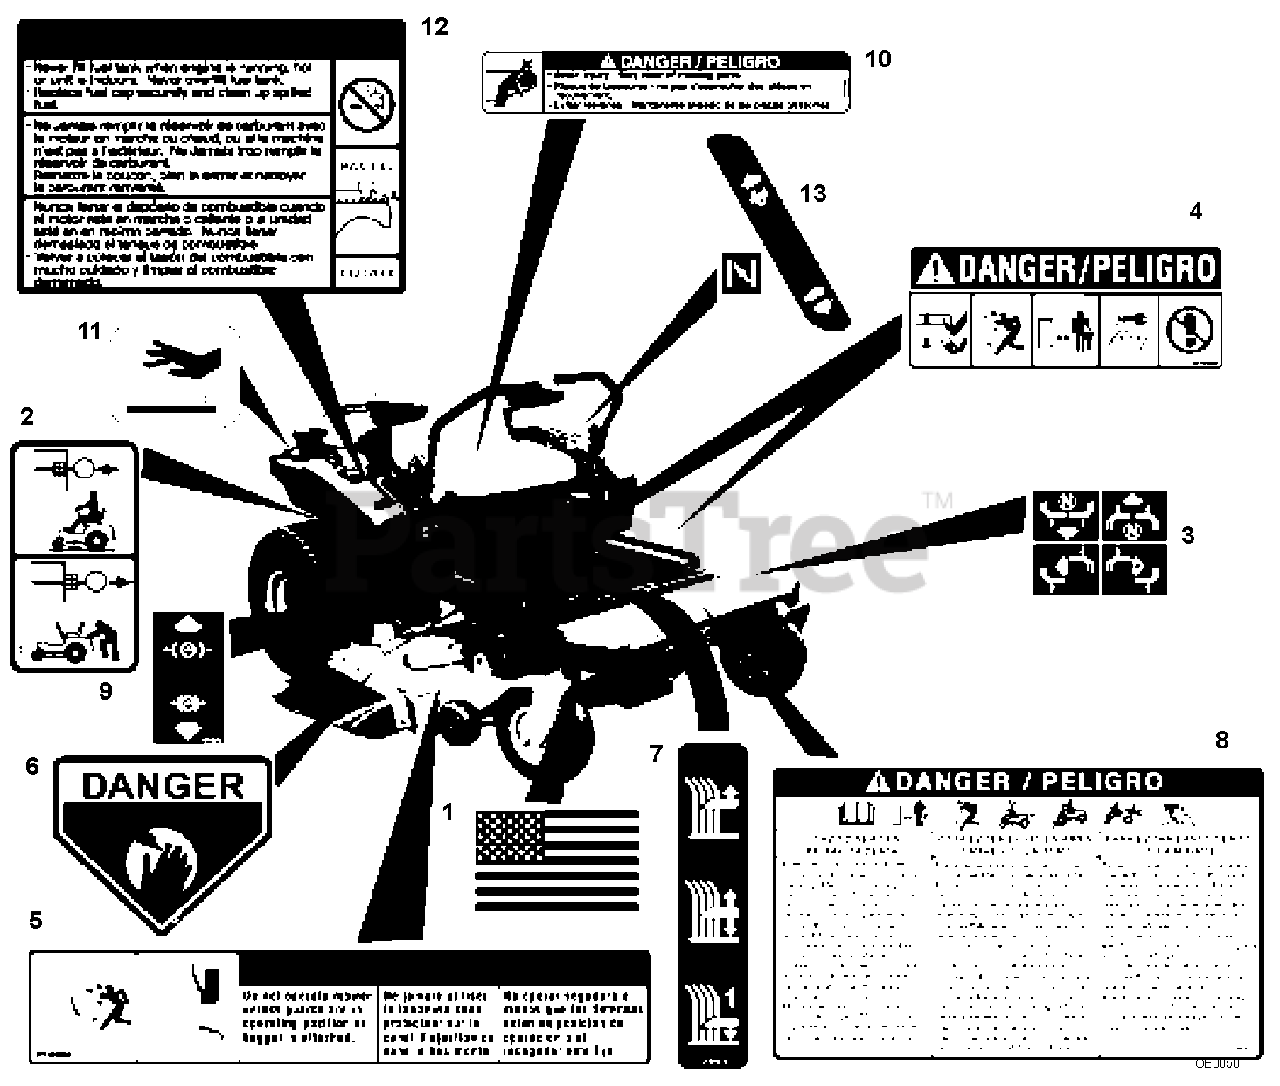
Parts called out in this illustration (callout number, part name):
1	Decal, American Flag
2	Decal, Transmission Disconnect
3	Decal, Instructional Steering
4	Decal, Mower Pan Danger
5	Decal, Warning
6	Decal, CPSC Danger
7	Decal, Cut Height
8	Decal, Bilingual Danger
9	Decal, Parking Brake Lever
10	Decal, Danger
11	Decal, Hot Surface
12	Decal, Fuel Warning
13	Decal, Control
